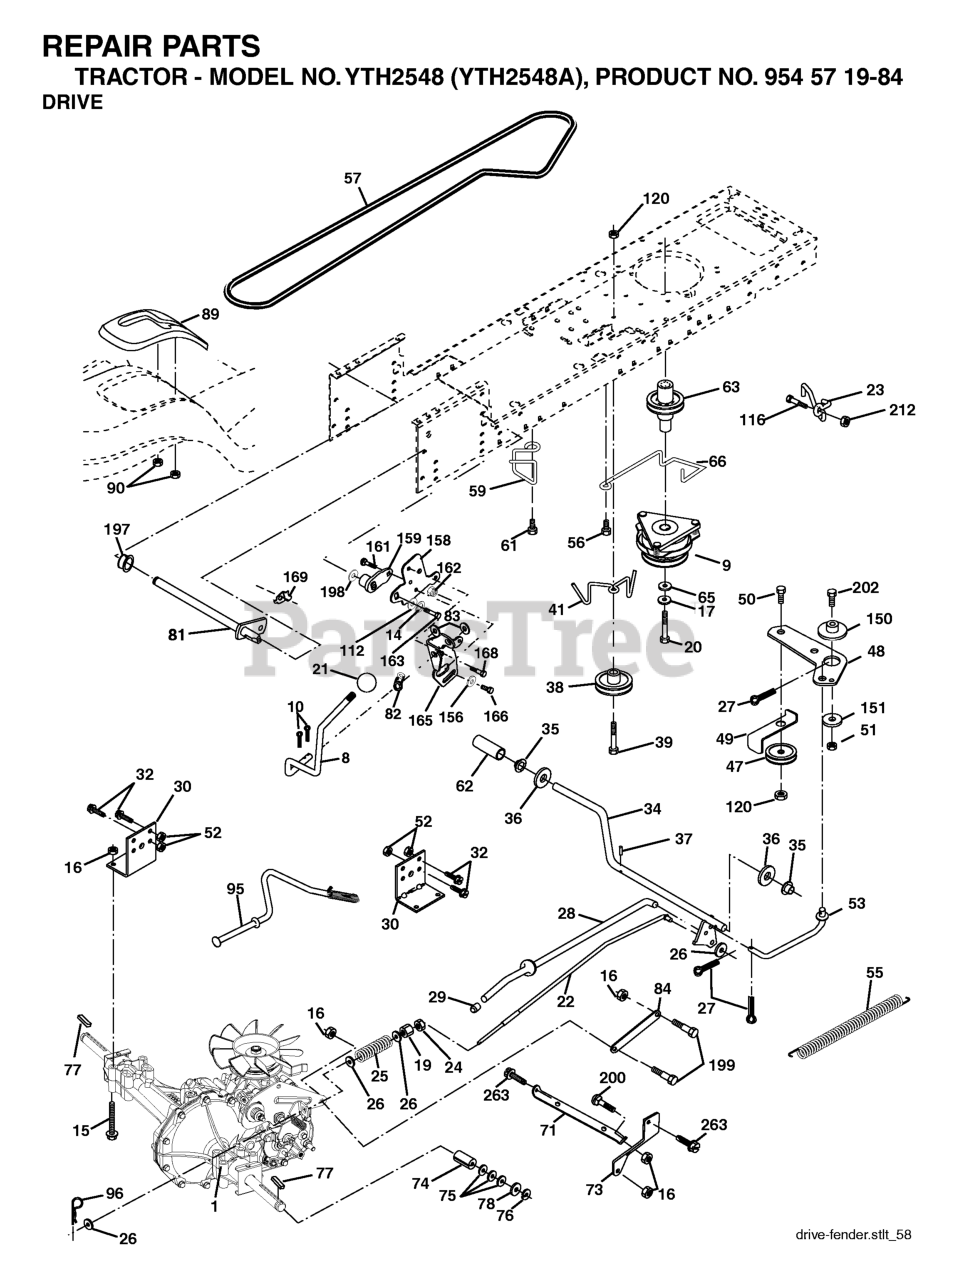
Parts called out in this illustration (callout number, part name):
8	ROD SHIFT FENDER ADJUST STLT
9	CLUTCH ELECTRIC
10	PIN COTTER
14	LOCKWASHER
15	BOLT HEX 5/16-18 GR 5
16	NUT.71038.31-18.HEX.NYLOCK
19	NUT
20	BOLT HEX 7/16-20X4-1/4"
21	KNOB.DELUXE.(PISTOL.GRIP).BLAC
22	ROD BRAKE HYDRO
23	BRKT ASM MTNG
24	NUT
25	SPRING ROD LT
26	WASHER
27	COTTER PIN
28	ROD, PARKING BRAKE
29	PLUNGER CAP
30	BRKT, TRNSXLE MNT 20"
32	BOLT
34	SHAFT, FOOT PEDAL
35	BEARING.NYLON
37	DRIVE PIN
38	PULLEY IDLER COMPOSITE
41	KEEPER, BELT IDLER
47	IDLER PULLEY
48	BELLCRANK, CLUTCH
49	RETAIN BELT
50	BOLT.3/8-16X1.50
52	LOCKNUT
53	LINK, CLUTCH LT
55	SPRING, RETURN LT
56	SCREW.3/8-16
57	DRIVE BELT, LTH & YTH TRACTORS
59	KEEPER, BELT CENTER
61	SCREW 3/8-16X.875
62	PEDAL COVER T
63	PULLEY- ENGINE
65	LOCKWASHER
66	KEEPER BELT ENGINE
71	STRAP TORQUE LH HYDRO
73	STRAP TORQUE RH HYDRO
74	SPACER AXLE
77	SQUARE KEY
81	SHAFT ASM CROSS TAPERED
82	SHIFT SPRING
83	WASHER
84	LINK TRANSAXLE
89	SHIFT CONSOLE
90	NUT.PUSH.3/16
95	CONTROL ASM. BYPASS HYDRO
96	RETAINER M
116	BOLT D
120	NUT LOCK FLG 3/8-16 UNC
150	SPACER, RETAINER
151	WASHER 12/32X2X10GA
156	WASHER.SRRTD.5/16
158	BRACKET
159	RB HUB.SHIFT
161	BOLT
162	NUT.CROWNLOCK.1/4
165	RP BRACKET
166	CAPSCREW.HXHD.FLG.5/16-18X.625
168	BOLT.SHOULDER.5/16-18X
169	PLATE.FASTENING.CROSS.SHAFT
197	NYLINER SNAP 5/8" ID
198	WASHER.NYL.7/8IDX.105"HYD CR
199	BOLT SHOULDER 5/16-18 UNC
212	NUT
263	SCREW, 3/8-16X3/4
